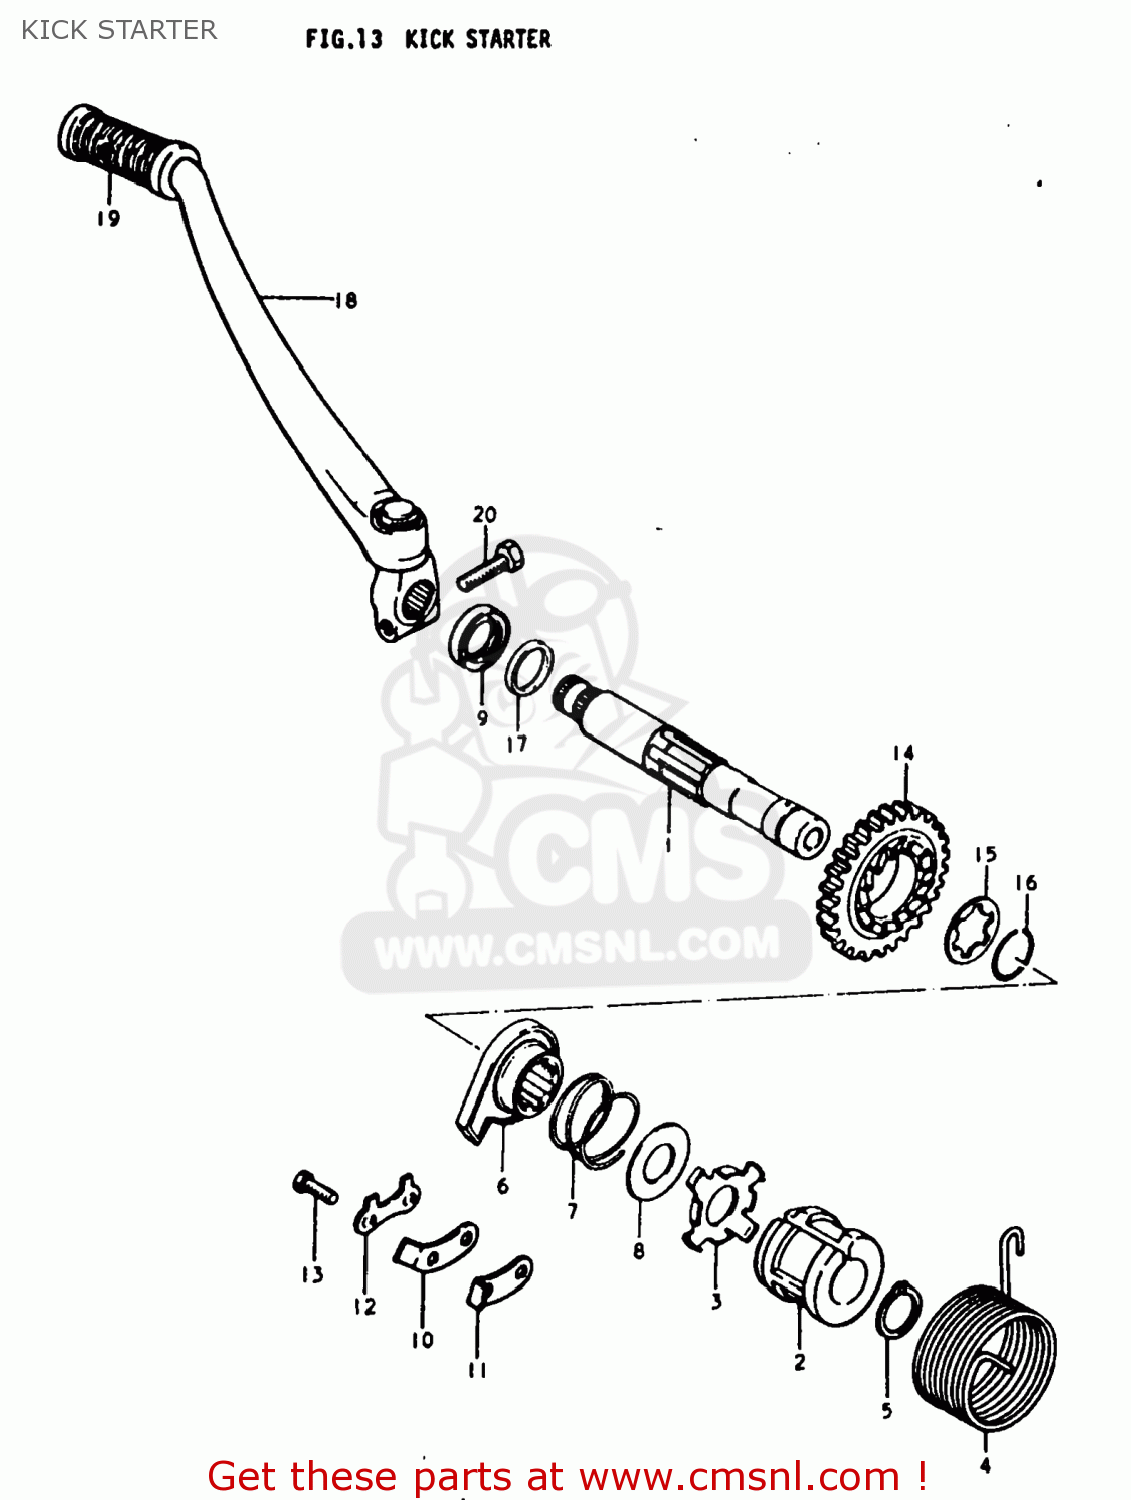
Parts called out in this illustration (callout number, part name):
1	SHAFT,KICK STARTER
2	GUIDE,KICK SHAFT SPRING
3	HOLDER,KICK SHAFT SPRING
4	SPRING
5	CIRCLIP
6	STARTER,KICK
7	SPRING
8	WASHER
9	SEAL,OIL(20X37X7)
10	GUIDE,KICK STARTER
11	STOPPER,KICK STARTER
12	WASHER
13	BOLT, UPPER
14	GEAR,KICK STARTER DRIVE
15	WASHER,LOCK
16	CIRCLIP
17	SPACER(20X28X4.5)
18	LEVER ASSEMBLY,KICK STARTER
19	RUBBER,KICK STARTER PEDAL
20	BOLT
